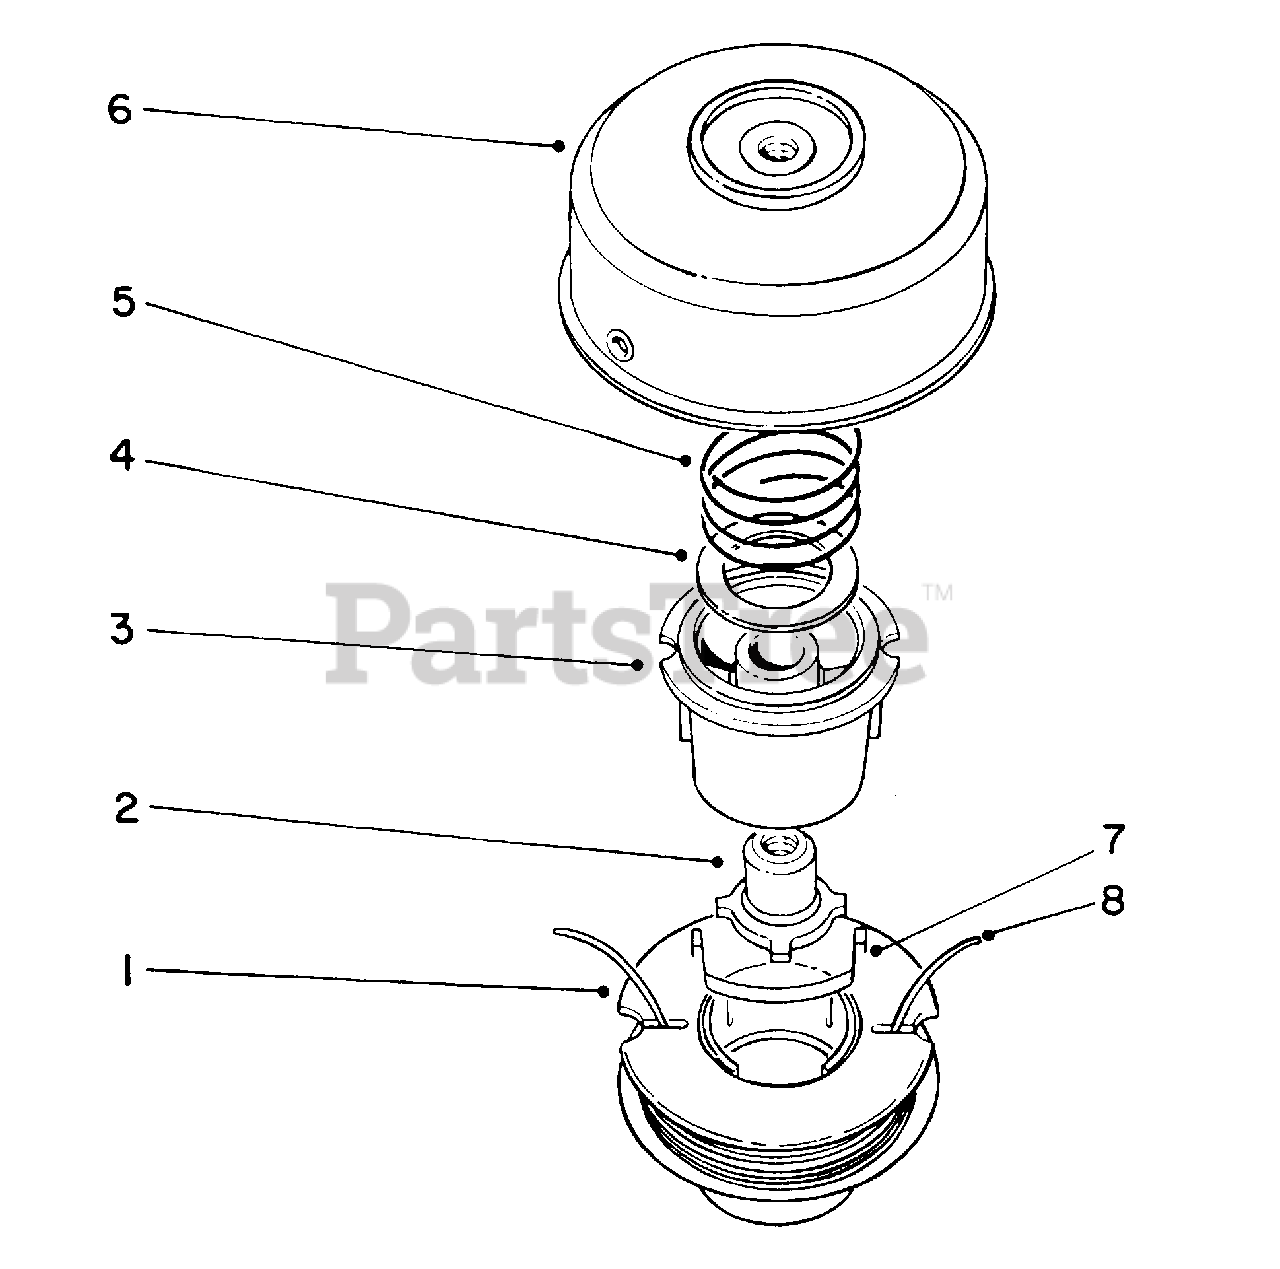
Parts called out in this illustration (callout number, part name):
1	Spool Prewound .08 Dia 38' (Incl. Ref. #7)
2	Driver L.H.
3	Spool Core
6	Drum w/Eyelets
7	Saddle-Spool Cap
